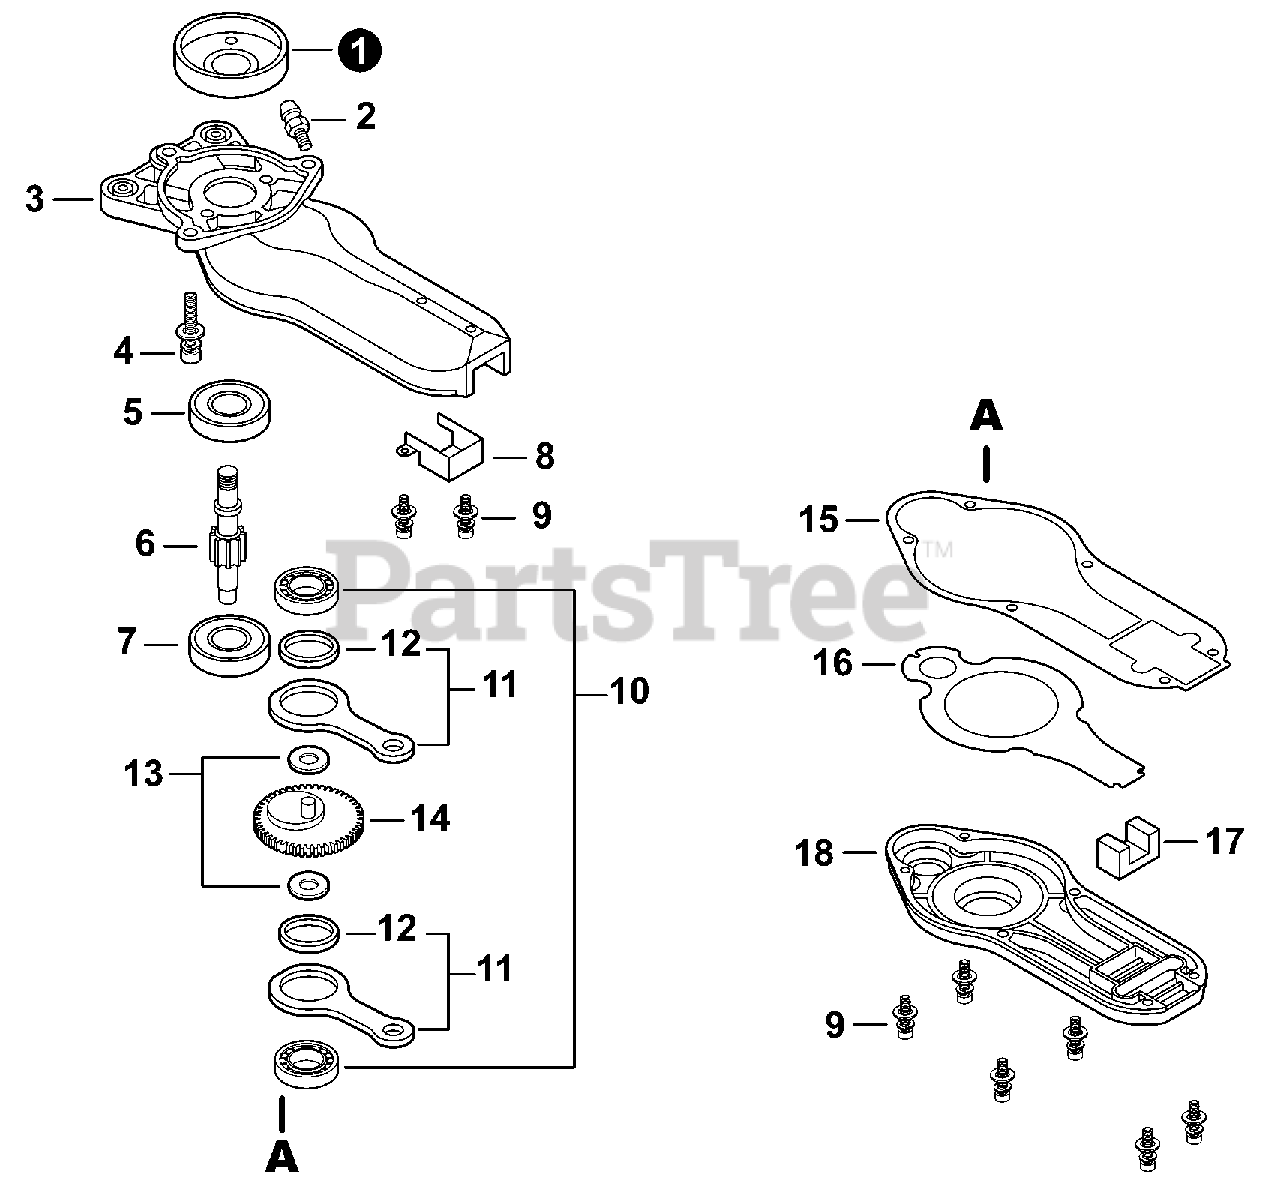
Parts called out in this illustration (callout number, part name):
1	DRUM, CLUTCH
2	FITTING, GREASE
3	CASE, GEAR - UPPER
4	BOLT 6×18
5	BEARING, BALL 6200
6	GEAR, SPUR
7	BEARING, BALL 608ZZ
8	GUIDE, BLADE
9	BOLT 4×16
10	BEARING, BALL 6200
11	ROD, CONNECTING
12	BEARING, NEEDLE 30
13	WASHER, THRUST 10
14	GEAR, SPUR
15	GASKET, GEAR CASE
16	PLATE, GEAR CASE
18	COVER, GEAR CASE
